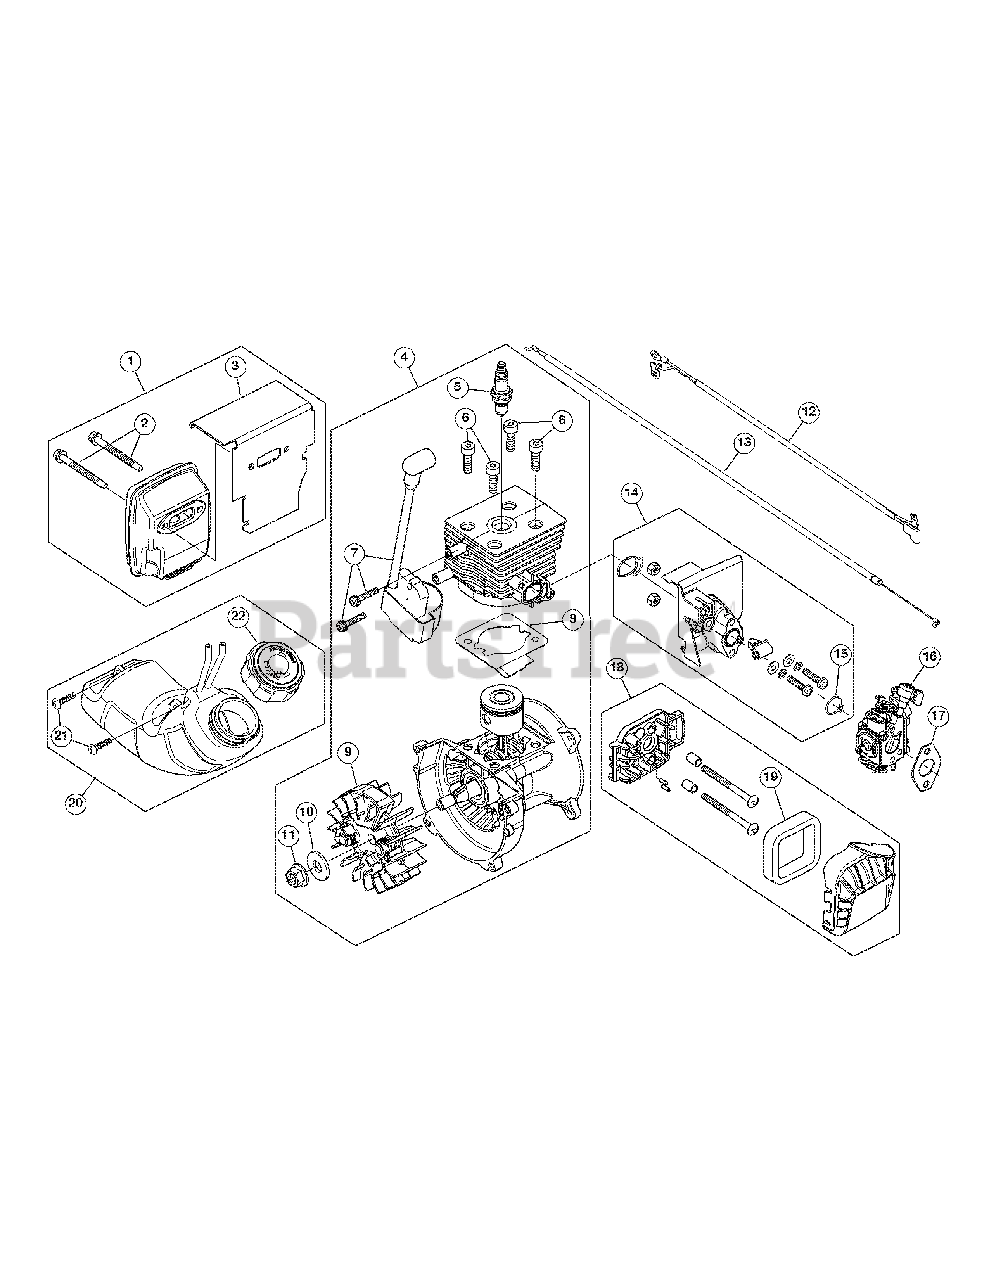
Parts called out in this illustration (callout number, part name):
1	Muffler Assembly (Incl. 2 & 3)
2	Muffler Screws
3	Muffler Gasket
4	Shortblock Assembly (Incl. 5 - 11)
5	Spark Plug
7	Module Assembly
8	Cylinder Gasket
9	Flywheel Assembly
10	Washer
12	Lead Wire
13	Throttle Cable
14	Insulator Assembly (Incl. 15)
15	Insulator O-Ring
16	Carburetor Assembly (Incl. 17)
17	Carburetor Gasket
18	Aircleaner Assembly (Incl. 19)
19	Air Filter
20	Fuel Tank Assembly (Incl. 21 & 22)
22	Fuel Cap
